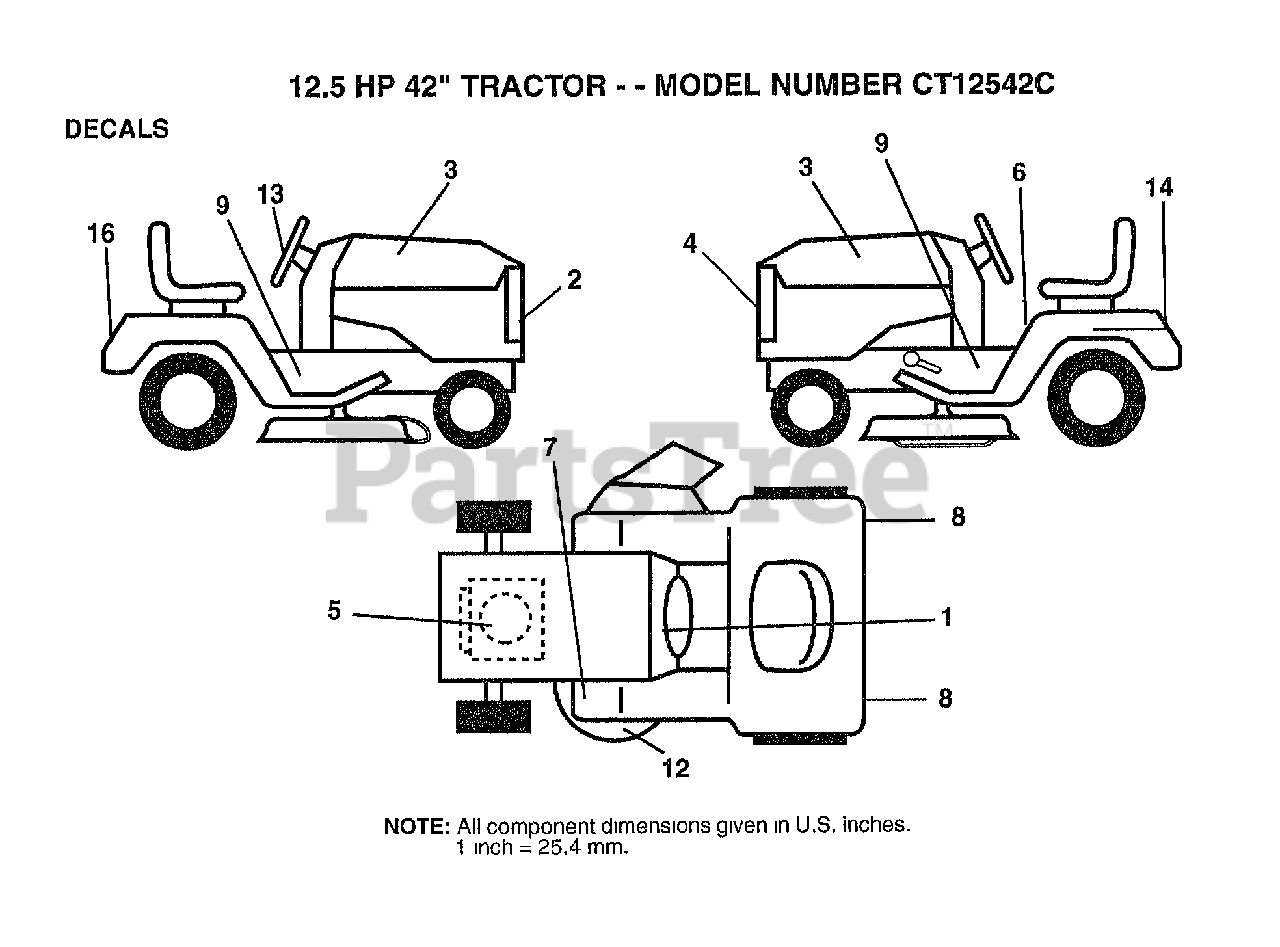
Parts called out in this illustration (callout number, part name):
2	DECAL.GRILLE
3	"DECAL, HP HOOD"
6	DECAL
8	REFLECTOR-TAIL YT
9	CHASSIS DECAL
13	DECAL.STG.WHL.INS
14	DECAL
16	DECAL.FENDER
